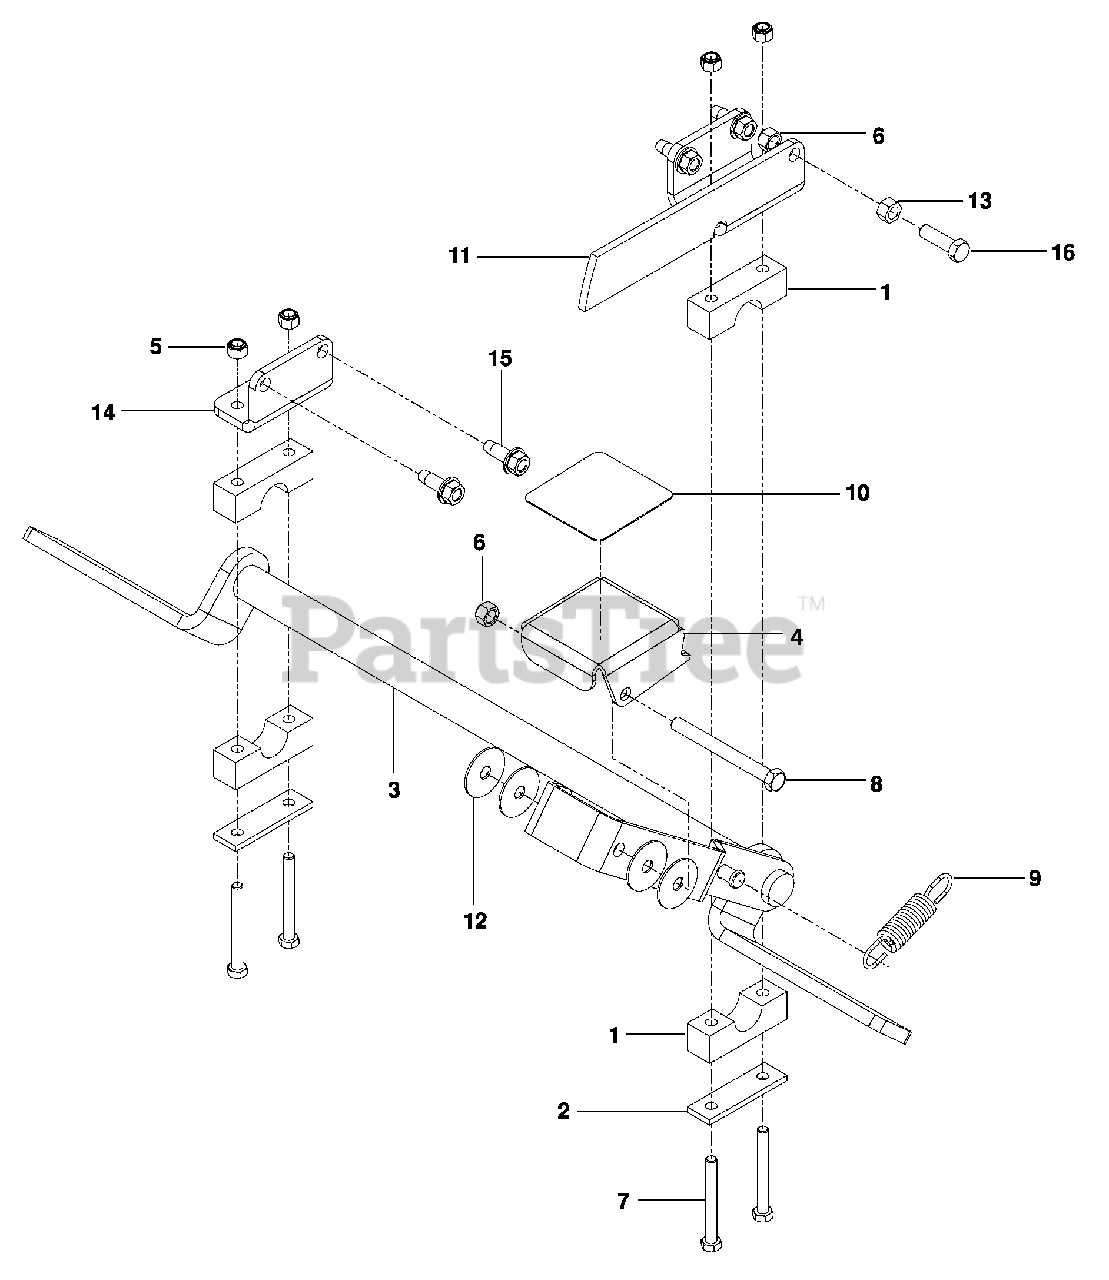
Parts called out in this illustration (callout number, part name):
1	PILLOW BLOCK
2	BAR, REINFORCEMENT
3	BRAKE ASSY
5	NUT 5/16-18 HEX NYLOC
6	NUT 3/8-16 HEX NYLOC
7	HCS 5/16-18 x 2¾
8	HCS 3/8-16 x 3¾
9	SPRING, EXTENSION
10	PAD, ANTI-SKID
11	PLATE, SUPPORT RH
12	WASHER, FRICTION
13	NUT 3/8-16 HEX
14	PLATE, SUPPORT LH
15	BOLT 3/8-16 x 1 THD FRM
16	HCS 3/8-16 x 1¼
